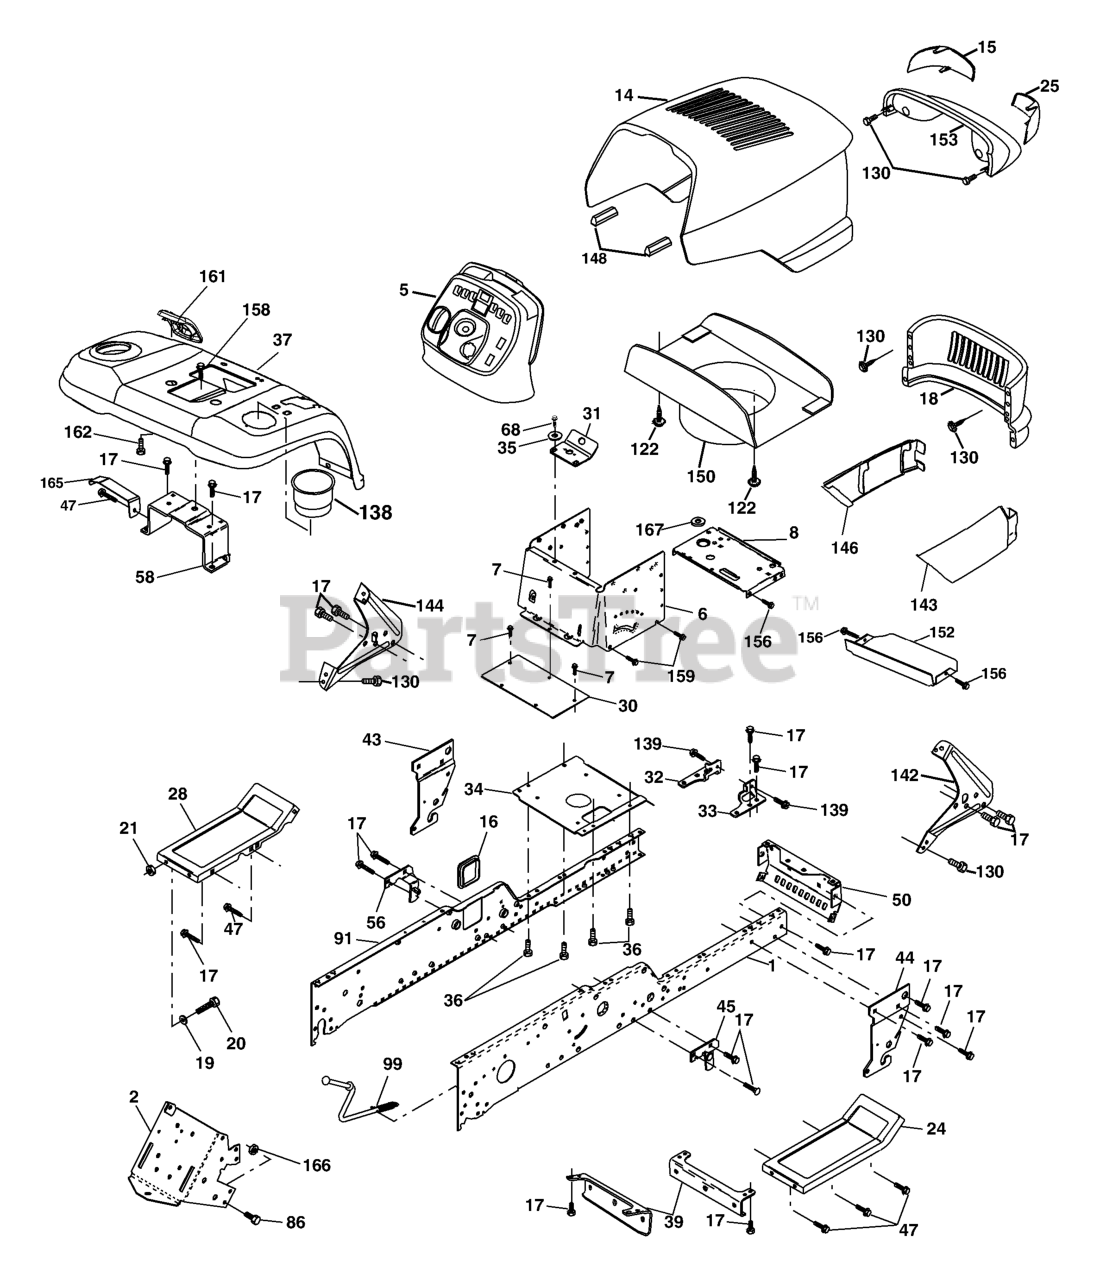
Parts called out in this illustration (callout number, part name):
1	KIT.RAIL.CHASS.RH.GT
2	DRAWBAR, GT
5	DASH, PLASTIC
6	DASH VGT, LOWER
7	SCREW
8	SUPPORT, BATTERY
14	HOOD
15	LENS LH
16	COVER ACCESS
17	SCREW, 3/8-16X3/4
18	GRILLE.STEALTH P/L.YTGT.GREY
19	WASHER
20	BOLT
21	NUT
24	FOOTREST PNT RH
25	LENS RH
28	FOOTREST PNT LH
30	SADDLE.HYDRO.95
31	BRACKET SUPT 1-PC VGT STEERING
34	PLATE ASM ENG CHASSIS
35	WASHER
36	SCREW 5/16"
37	FENDER, PNT
39	BRACKET AXLE, FRONT
43	FRONT SUSPENSION BRKT LH
44	FRONT SUSPENSION BRKT RH
45	BRACKET, ASM., SUSP CHASSIS RH
47	SCREW LT
50	BRACKET, CHASSIS FRONT
56	BRACKET ASM., SUSP CHASSIS LH
58	BRACKET ASM., FENDER
68	Screw, 5/16-18 x 1/2
91	KIT.RAIL.CHASS.LH.GT
99	ROD ASM, BYPASS
122	SCREW.HEX.WS.HD.8-18 X 7/8
130	SCREW
138	CUPHOLDER
139	BOLT, SHOULDER 5/16-18
142	BRACKET DASH STEALTH(R)
143	SKIRT GRILLE RH
144	BRACKET DASH STEALTH LH
146	SKIRT GRILLE LH
148	EXTRUSION BUMPER (3 2) (2 2)
150	DUCT.HEAT.HOOD.STEALTH.GT
152	BROWNING SHIELD
153	LIGHTBOX.ASM.STV.DL.INC.HUSQ
156	SCREW
158	SCREW 3/8-16X1/2
159	SCREW, 3/8-16X3/4
161	CONSOL.FUEL.WINDOW.BLACK
162	SCREW.HI-LO.CONSOLE
165	BRACKET SUPPORT TANK
166	Nut, Crown Lock 7/16-14 unc
167	BUSHING SNAP
